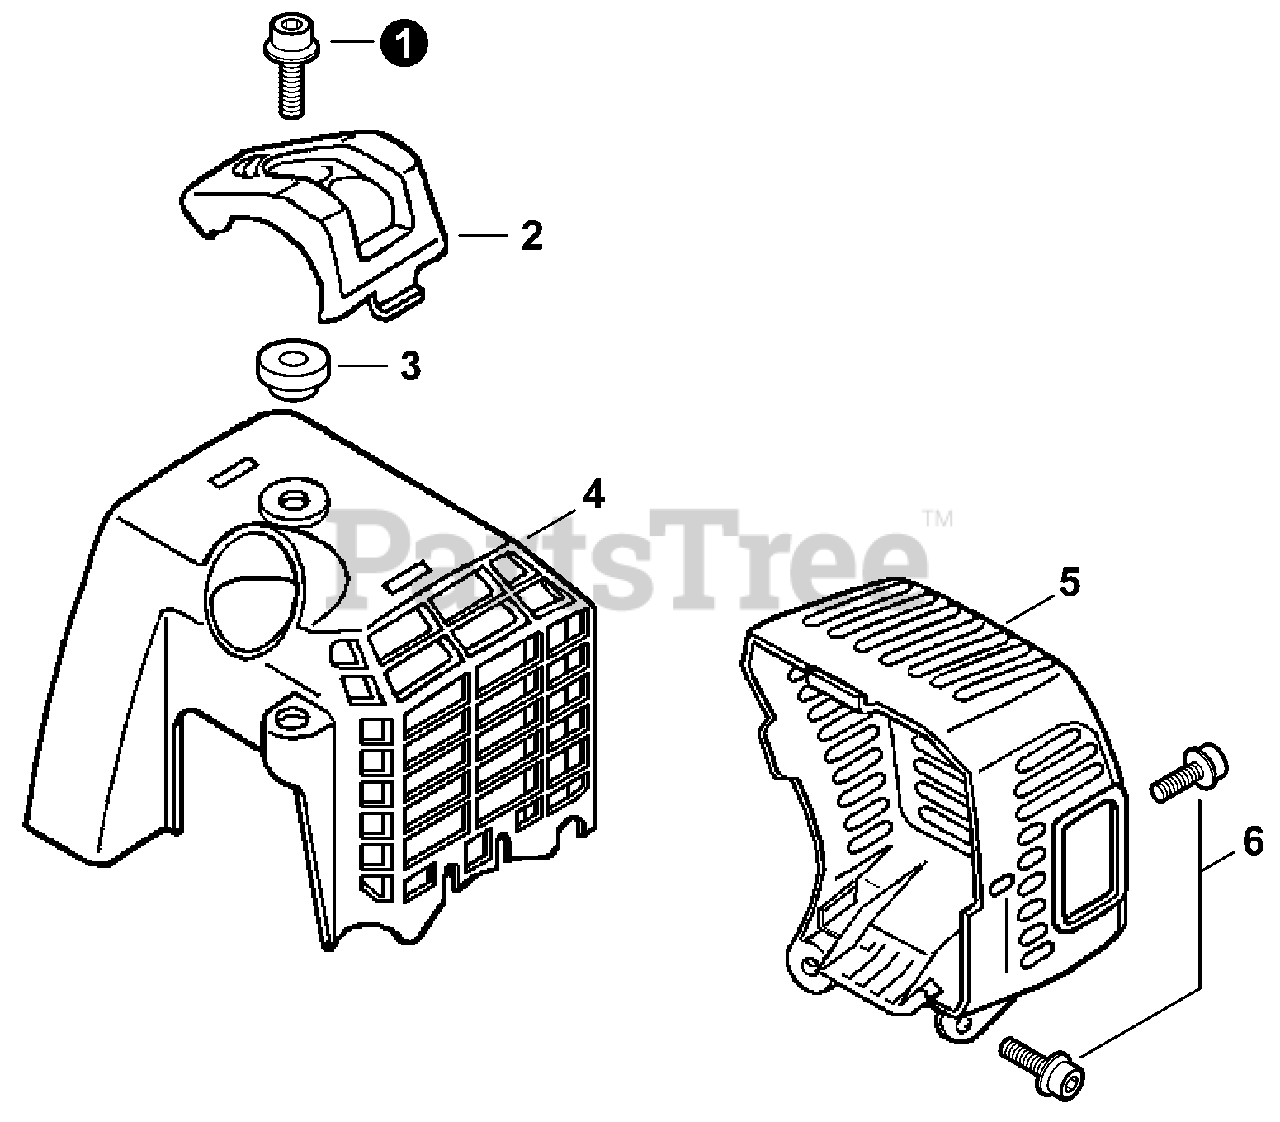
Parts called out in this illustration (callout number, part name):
1	BOLT 5×16
2	GUARD, TOP
3	COLLAR 5
4	COVER, ENGINE - ORANGE
5	COVER, MUFFLER
6	BOLT 5×12
